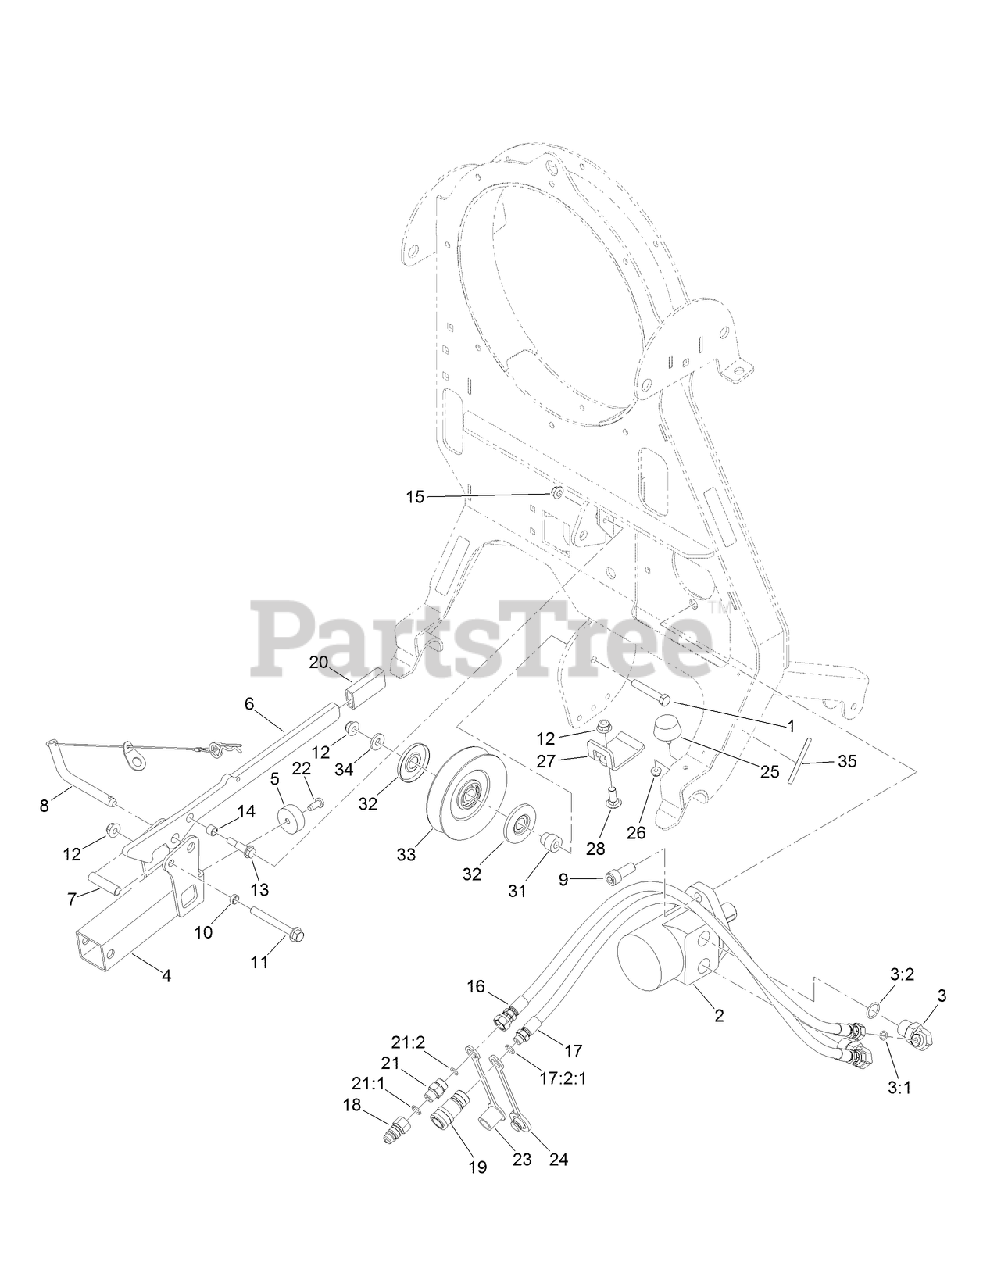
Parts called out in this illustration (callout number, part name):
1	SCREW-HH
2	HYD MOTOR ASM
3	FITTING-ELBOW 90
3:1	O-RING
3:2	O-RING
4	BLOWER HITCH ASM
5	BUMPER-RUBBER
6	HANDLE-LATCH
7	SPACER-ROLLER
8	PIN-ROPS W/ LANYARD
9	SCREW-HSH
10	SPACER
11	SCREW-HHF
12	NUT-HF, NI
13	SCREW-SHOULDER
14	BUSHING
15	NUT-HF, NI
16	HOSE ASM
17	HOSE ASM
17:2:1	O-RING
18	NIPPLE-DISCONNECT, QUICK
19	COUPLER-DISCONNECT, QUICK
20	GRIP-FLAT
21	FITTING-STRAIGHT
21:1	O-RING
21:2	O-RING
22	SCREW-BHTF
23	CAP-DUST
24	PLUG-DUST
25	BUMPER
26	NUT-HF
27	BRACKET-STOP
28	SCREW-HH
31	BUSHING-IDLER
32	SHIELD-GUARD, DUST
33	PULLEY-IDLER
34	WASHER-SPACER
35	DECAL-WARNING
